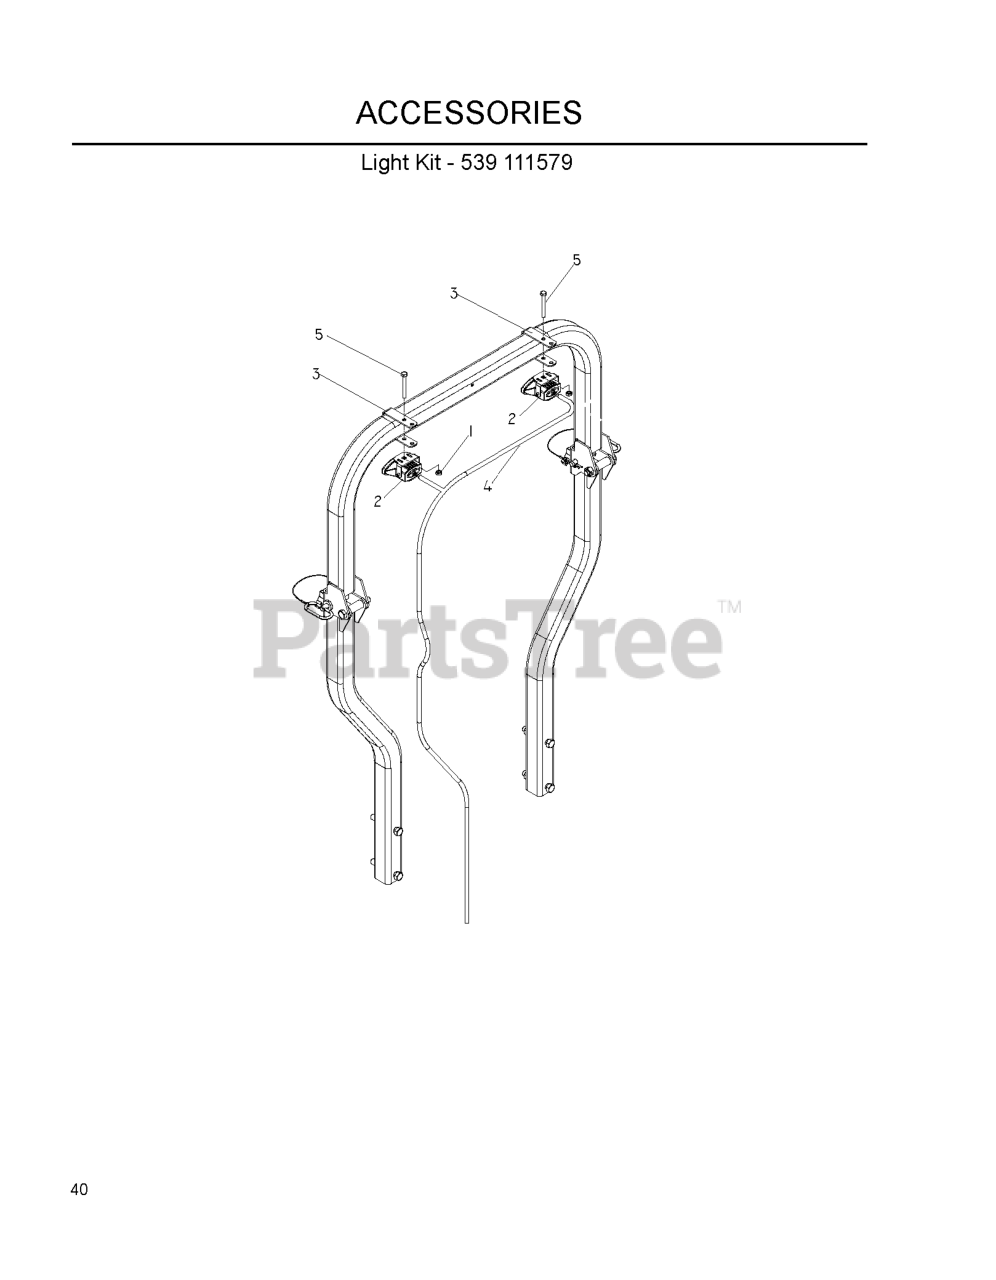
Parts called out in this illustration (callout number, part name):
1	NUT 5/16-18 HEX JAM ZD
2	LIGHT 35W W/BRKT
3	LIGHT MOUNTING BRACKET
4	LIGHT HARNESS
5	BOLT 5/16C X 2 1/2
